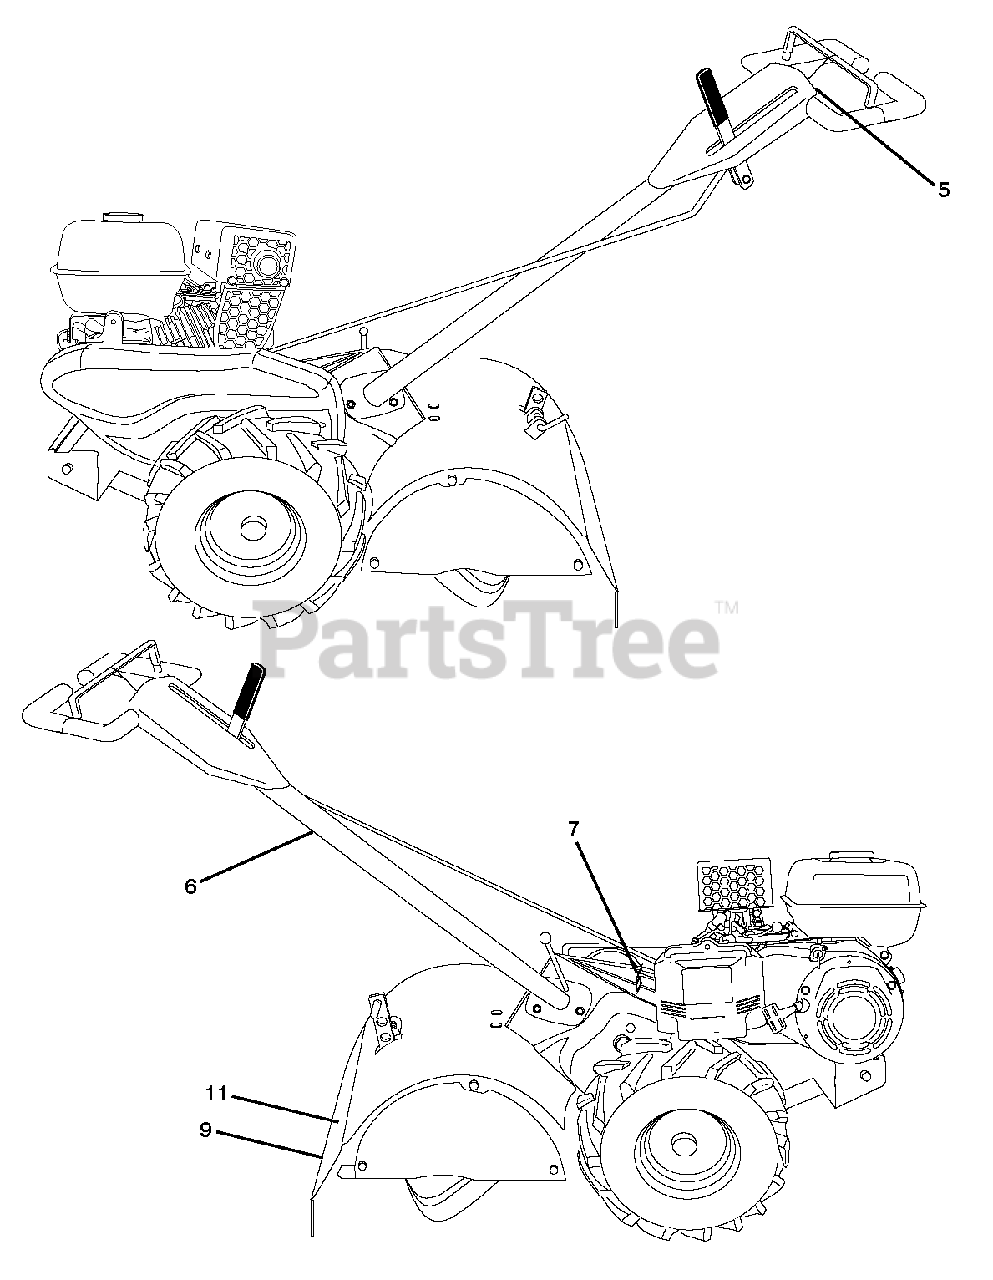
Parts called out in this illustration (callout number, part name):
6	DECAL TI
7	DECAL.SHIFT.INDICATOR.TILLER
11	DECAL WARNING
